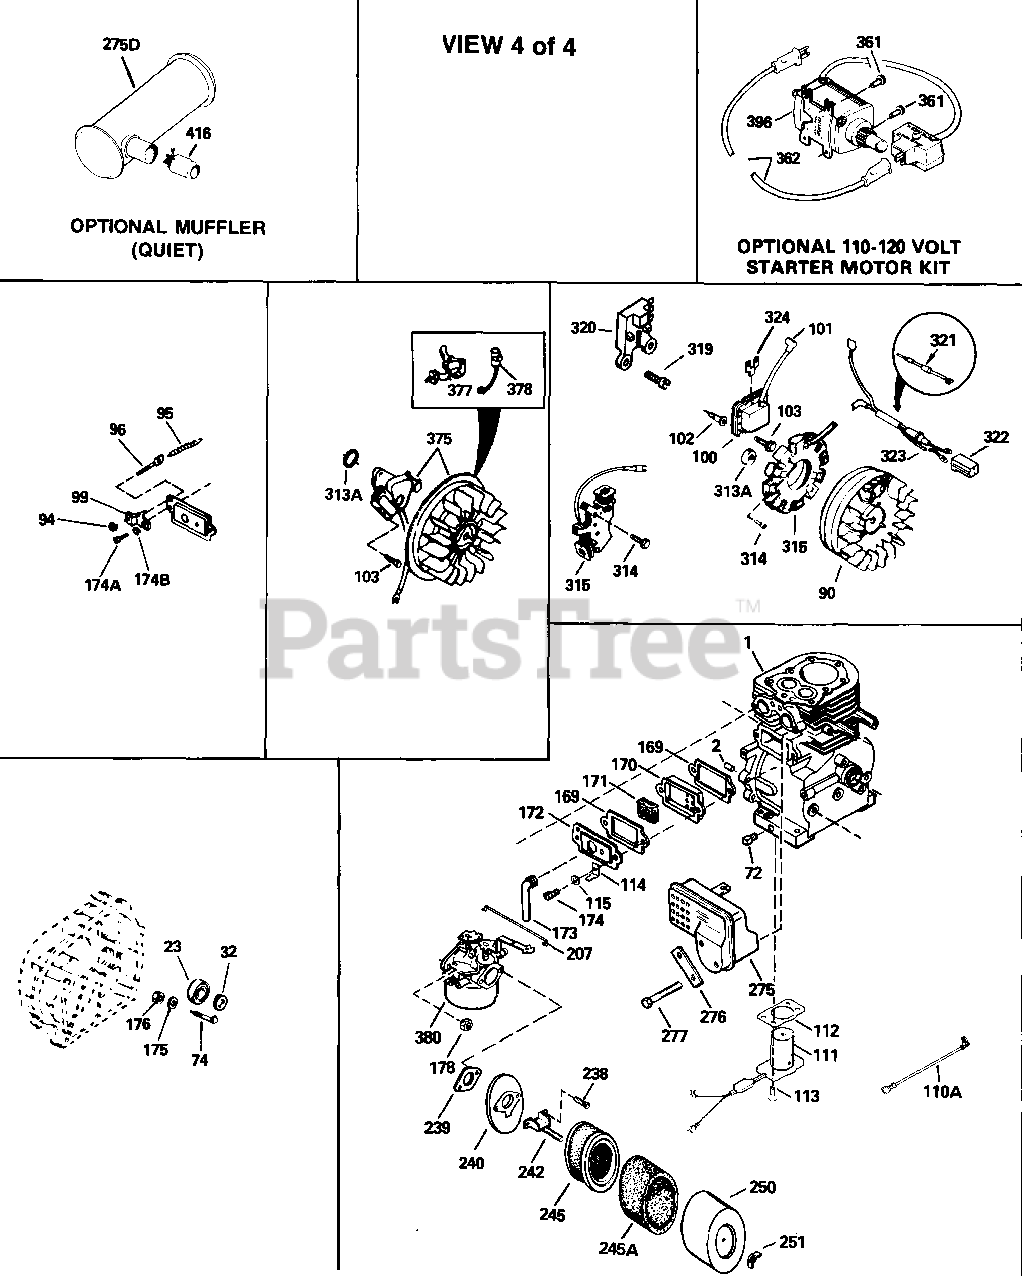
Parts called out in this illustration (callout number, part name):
1	"Cylinder (CI liner)(3-5/16") Incl. 2, 2 0 & 72
2	Dowel Pin
37A	Lock Nut, 8-32
72	Oil Drain Plug (Sq. hd., 1/4-18)
90	Flywheel (w/ring gear)
94	Lock Nut, 10-32
95	Spring, Governor bolt
96	Bolt, Governor adjusting
100	Solid State Ignition
101	Spark Plug Cover
102	Stud, Solid state mounting
103	Screw, Torx T-15, 10-24 x 1"
169	* Gasket, Breather
170	Breather Body
171	Breather Element
172	Valve Cover
173	Breather Tube
174	Screw, 10-24 x 1/2"
178	Nut & Lock Washer 1/4-28
207	Link, Governor lever-to-throttle
222A	Pop Rivet (Can be purchased locally)
238	Screw, 10-32 x 1/2"
239	* Gasket, Air cleaner
241	Bracket, Air cleaner
242	Bracket, Air cleaner
245	Air Filter (Paper) also available in Packaged Part #740027B
251	Nut, Wing 1/4-20
276	Locking Plate
277	Screw, 5/16-18 x 3-3/16" Use as requi red
277	Screw, 5/16-18 x 4-1/4" Use as requir ed
313A	Gasket, Stator Used only on Std. poi nt ign.
338A	Plug, Cover
377	Breaker Points (also available in Pac kaged Part #740037B) gn.)
380	Carburetor (Incl. 184 & 379) (Refer t o Division 5, Section A, page A4-4 fo r breakdown or Fiche 18B, Grid D-3)
421	SAE 5W30 4-Cycle Engine Oil - Quart - Winter
422	Muffler Optional
